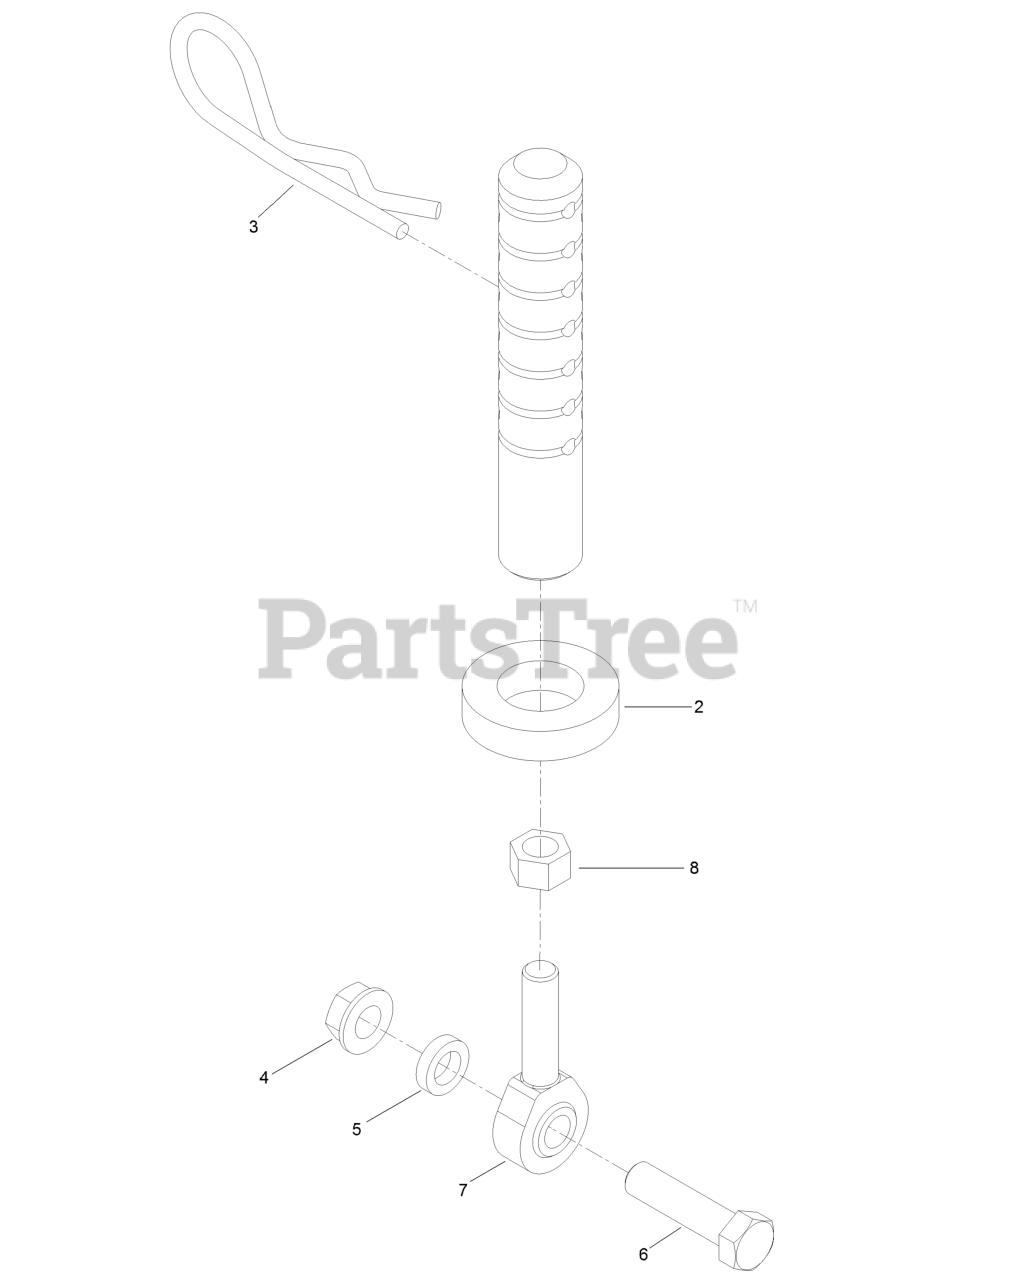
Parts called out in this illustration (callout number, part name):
2	Spacer-Deck Support
3	Pin-Cut Height
4	Nut-HHF, Whiz
5	Spacer-Idler
6	Screw-HH
7	Balljoint
8	Nut-HJ
